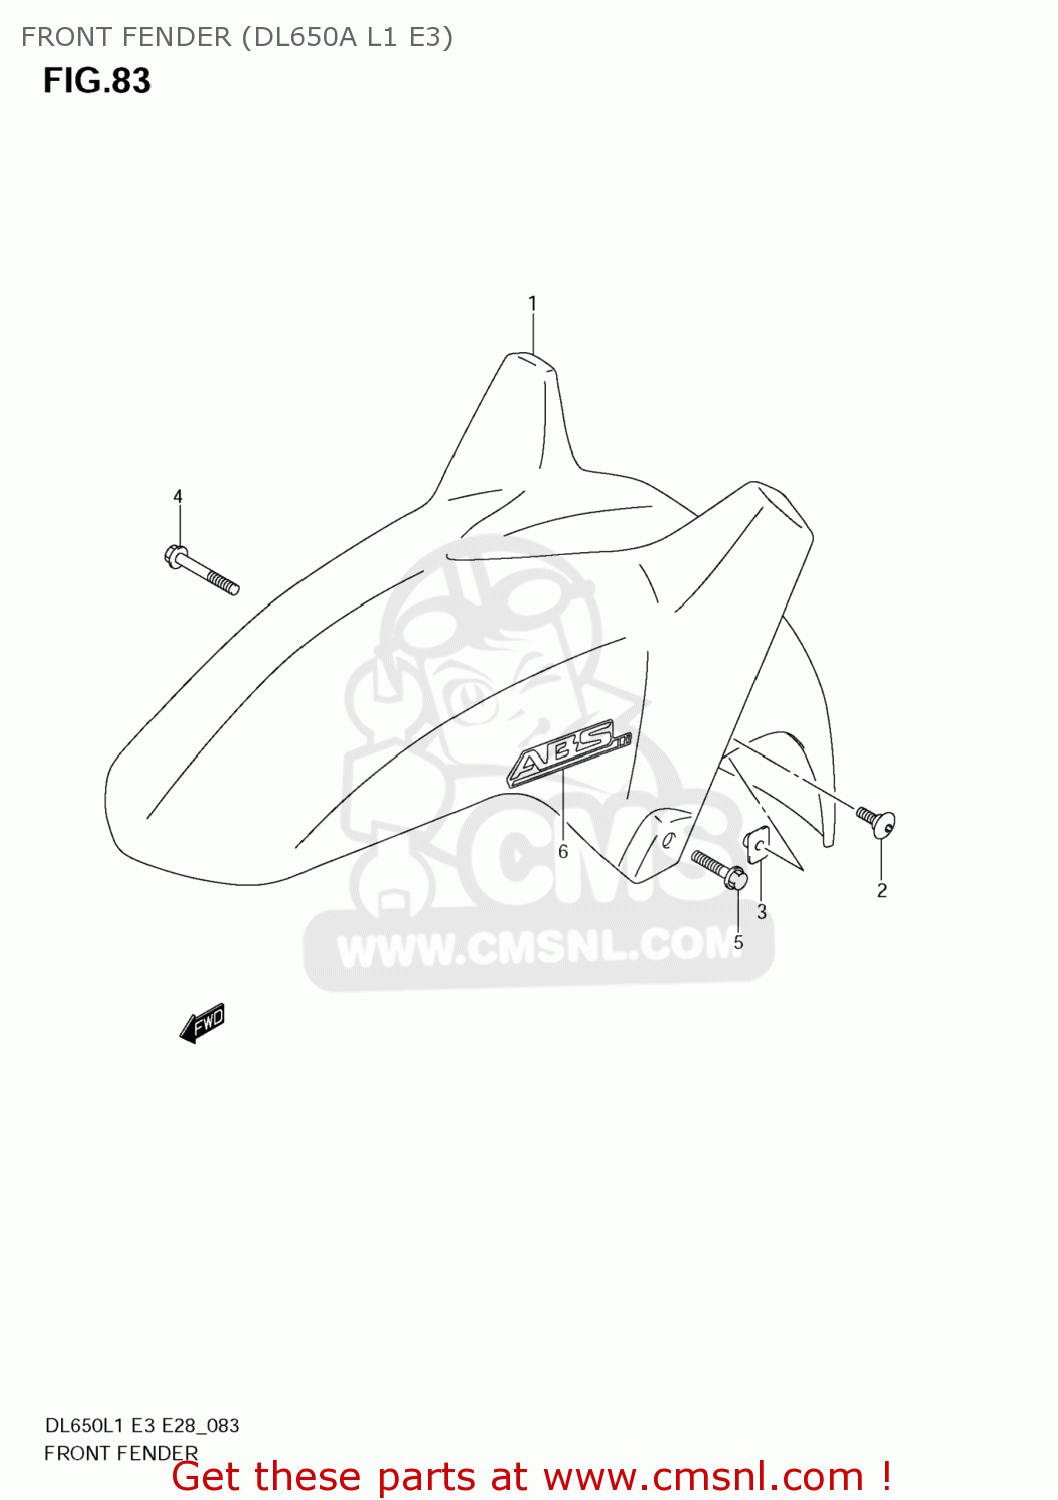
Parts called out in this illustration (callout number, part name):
1	FENDER,FR
2	SCREW(6X16)
3	NUT,FR FENDER
4	BOLT
5	BOLT
6	EMBLEM,ABS
